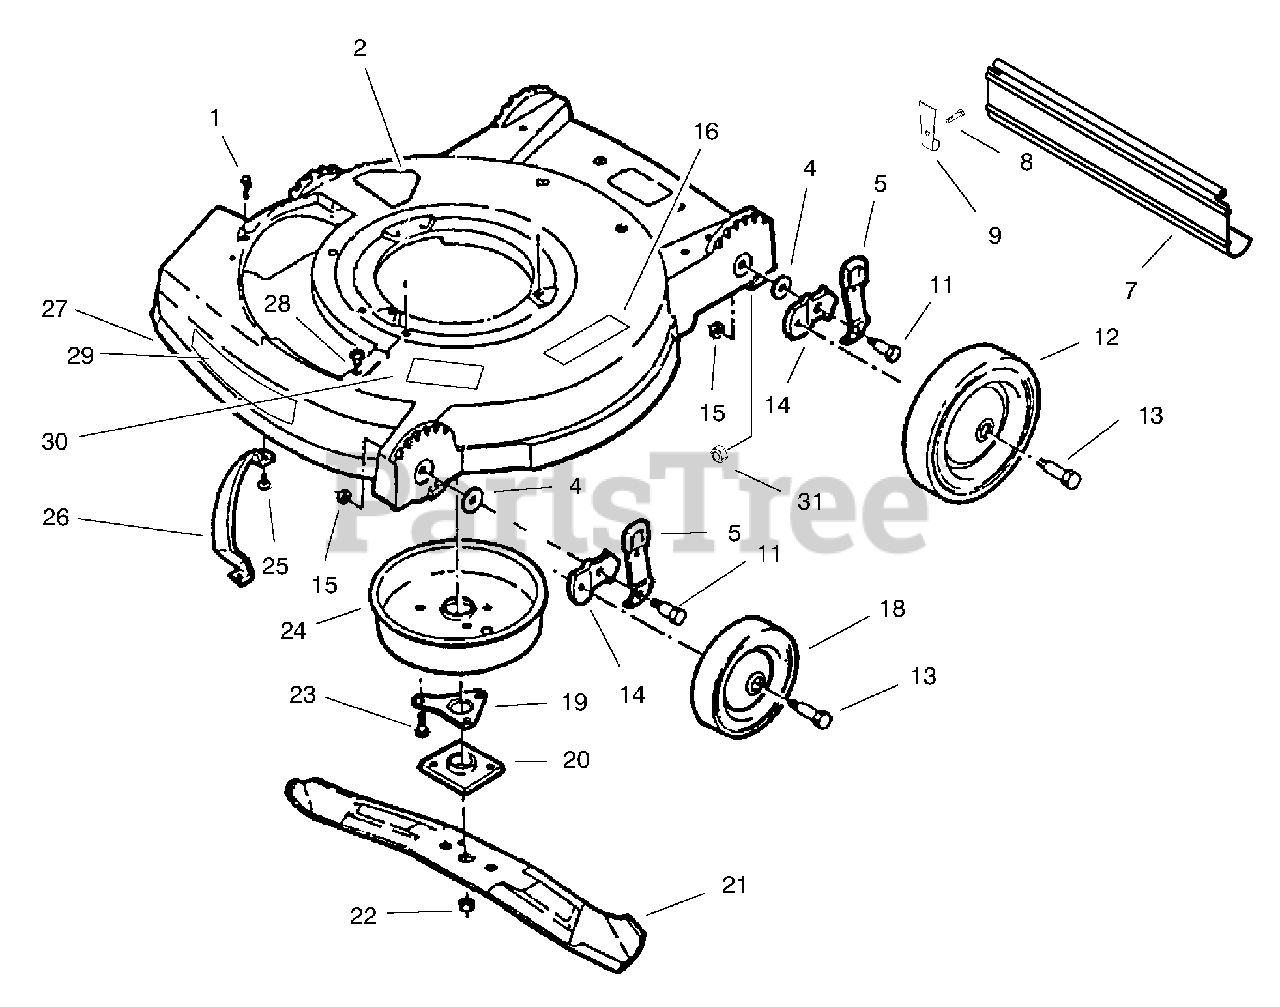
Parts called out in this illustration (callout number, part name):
1	Screw-SEMS, Plate Cover
2	Decal-Blade Warning
5	Knob & Spring-Adjustment
7	Shield-Trailing
8	Screw
9	Clamp-Rod, Shield
11	Bolt-Shoulder
12	Wheel-Rear, 8"
13	Bolt-Wheel
14	Bracket-Wheel Adjustment
15	Nut-Lock
16	Decal-Warning
18	Wheel-Front, 6"
19	Plate-Support, Crankshaft
20	Collar & Plate
21	Blade-21"
22	Nut-Blade
23	Screw-Plate to Muffler Cov.
24	Cover-Muffler
25	Screw-Toe Bar to Housing
26	Toe Bar
27	Assembly-Housing (Incl. Ref. #2, 16, 28, & 30)
30	Decal-No Rust
31	Nut-Lock
